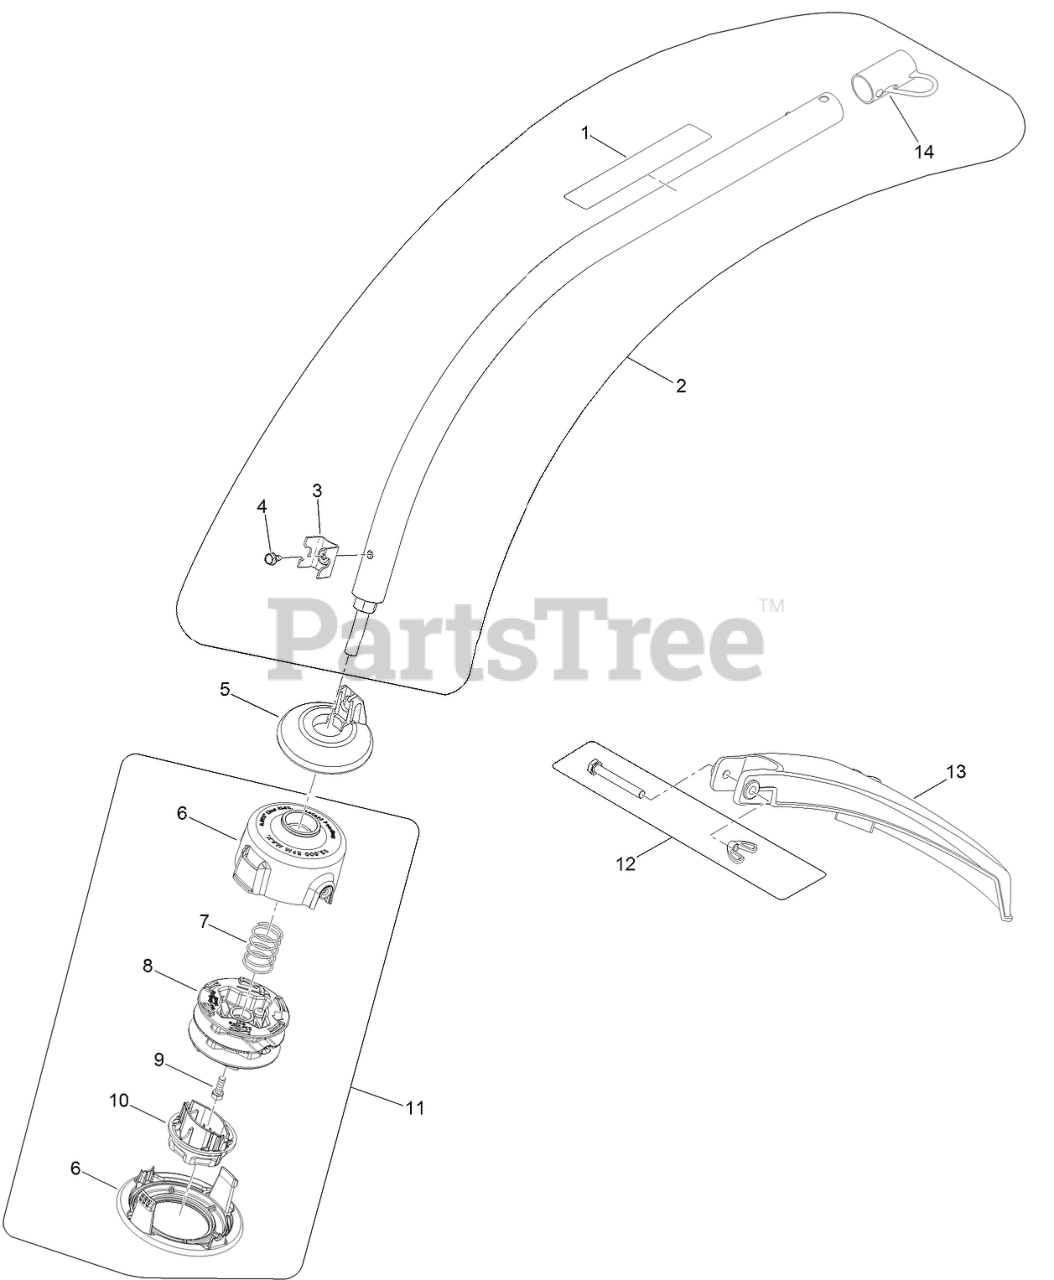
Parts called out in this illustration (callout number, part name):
1	DECAL-LABEL, WARNING
2	CURVED SHAFT ASM
4	SCREW-HWH
5	SHIELD-GRASS
6	HOUSING-STRINGHEAD
7	SPRING-COMPRESSION
8	SPOOL
10	KNOB-BUMP
11	TRIMMER HEAD ASM
12	GRASS SHIELD HARDWARE KIT
13	GUARD-TRIMMER
14	CAP-HANGER
